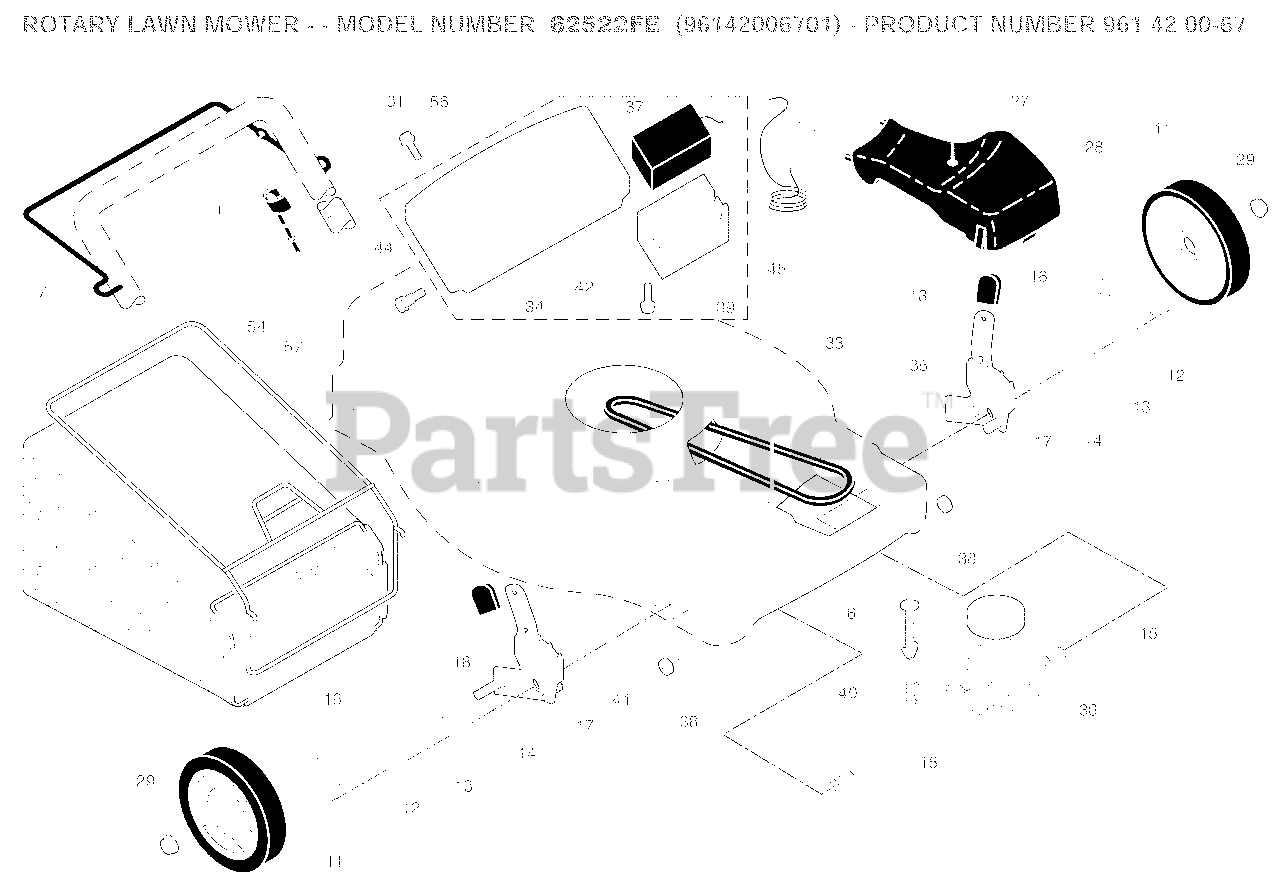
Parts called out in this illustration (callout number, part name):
1	Drive Control Cable
6	Retainer, Spring
7	Bar, Drive Control
11	Wheel & Tire Assembly
13	Gear, Pinion
14	Dust Cover
15	Pawl, Drive
16	Washer, Flat 3/8
17	Ball Bearing
18	Selector Knob
27	Pan Head Tapping Screw #10-24 x 2-3/4
28	Drive Cover
29	Locknut, Hex
31	Screw, Torx Pan Head #20
33	V-Belt
35	Kit, Wheel Adjuster, LH
36	Gear Case Assembly, Complete
37	Battery
38	Locknut, Hex 1/4-20
39	Box, Battery
41	Kit, Wheel Adjuster, RH
42	Screw, Hex Head #13 x 1/2
44	Screw, Shoulder, Hex Head #10-28 x 5/8
45	Charger, Battery
56	Trimplate / Battery / Battery Box Assembly
57	Frame, Grassbag
